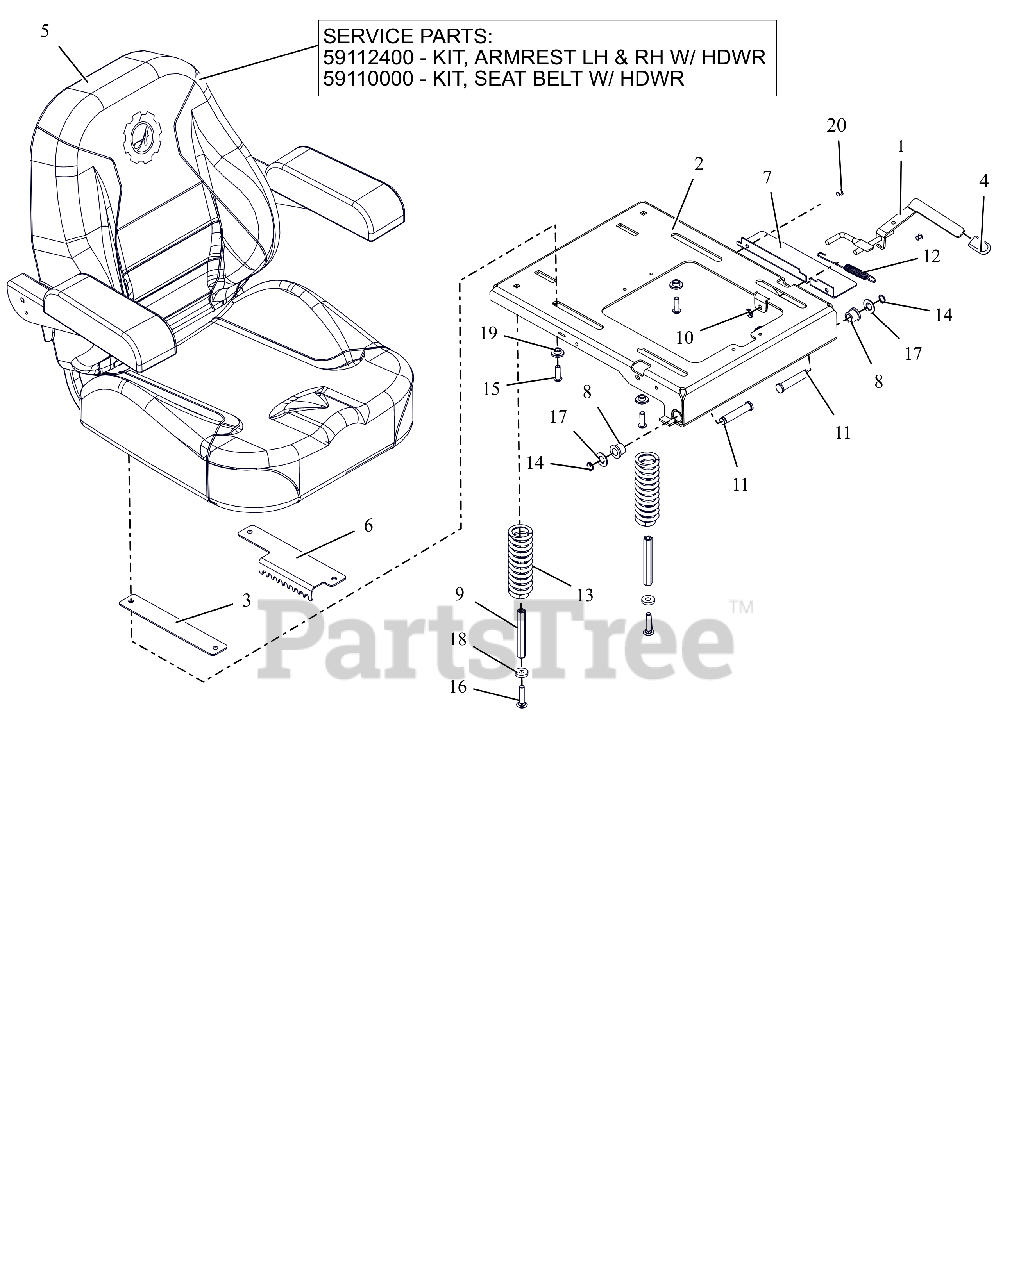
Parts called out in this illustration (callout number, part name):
1	WLDMT, SEAT SLIDE LEVER
2	WLDMT, SEAT PLATE HD
3	PLATE, ADJUSTABLE SEAT SLIDE
4	GRIP, SEAT LEVER, GREY
5	SEAT, APEX
5	KIT-LH & RH ARM REST-05124700
5	KIT-SEAT BELT REPLACE-05007300
6	PLATE, HD SEAT ADJUSTMENT
7	GUARD, SEAT PLATE
8	BSHG, FLG .516X.750X.625X.937
9	NUT, COUPLING 5/16X18 X 3.75
10	NUT-PUSH .312
11	PIN, SEAT PIVOT -.500X2.31
12	SG-TENS .06X.482X5.35
13	SPRING, COMPRESSION SEAT 224LB
14	RG-RTNG-EXT .500X.050 (SNAP)
15	BLT,SHCS-BTN .31-18X1.00 ZCC
16	BLT,RHSN .31-18X1.50 G5 ZCC
17	WSHR, FLT .531X1.00X.063 ZCC
18	WSHR, FLT .328X.870X.179 ZCC
19	BSHG-FLG .32X.500X.344X.880
20	RIVET, .1875 AL/AL .126-.250
